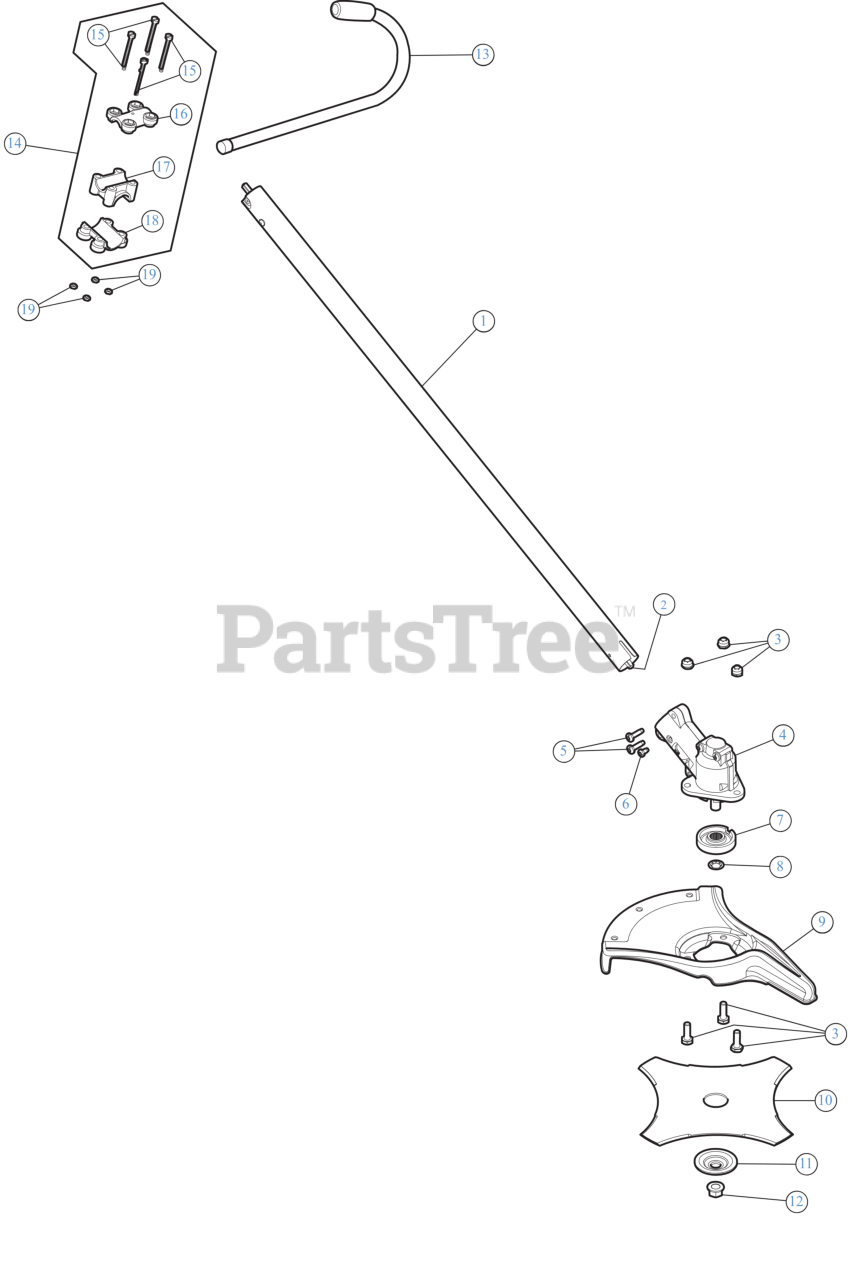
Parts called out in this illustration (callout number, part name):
1	LOWER SHAFT
2	LOWER DRIVE SHAFT
3	SCREW SET-GUARD MT
4	GEARBOX
5	SCREW #
6	SCREW, 8-32 x .312 P
7	SPACER-GEARBOX
8	PALNUT:3/8" DIAM
9	SHIELD-BLADE CAST
10	BLADE 4-TOOTH
11	WASHER-BLADE CLAMP BRUSH CUT
12	BLADE LOCK NUT
13	HANDLE ASSEMBLY-JAY
14	HANDLE BRACKET ASSEMBLY
15	CLAMP SCREW
16	HANDLE UPPER CLAMP
17	HANDLE MIDDLE CLAMP
18	HANDLE LOWER CLAMP
19	NUT-CLAMP
